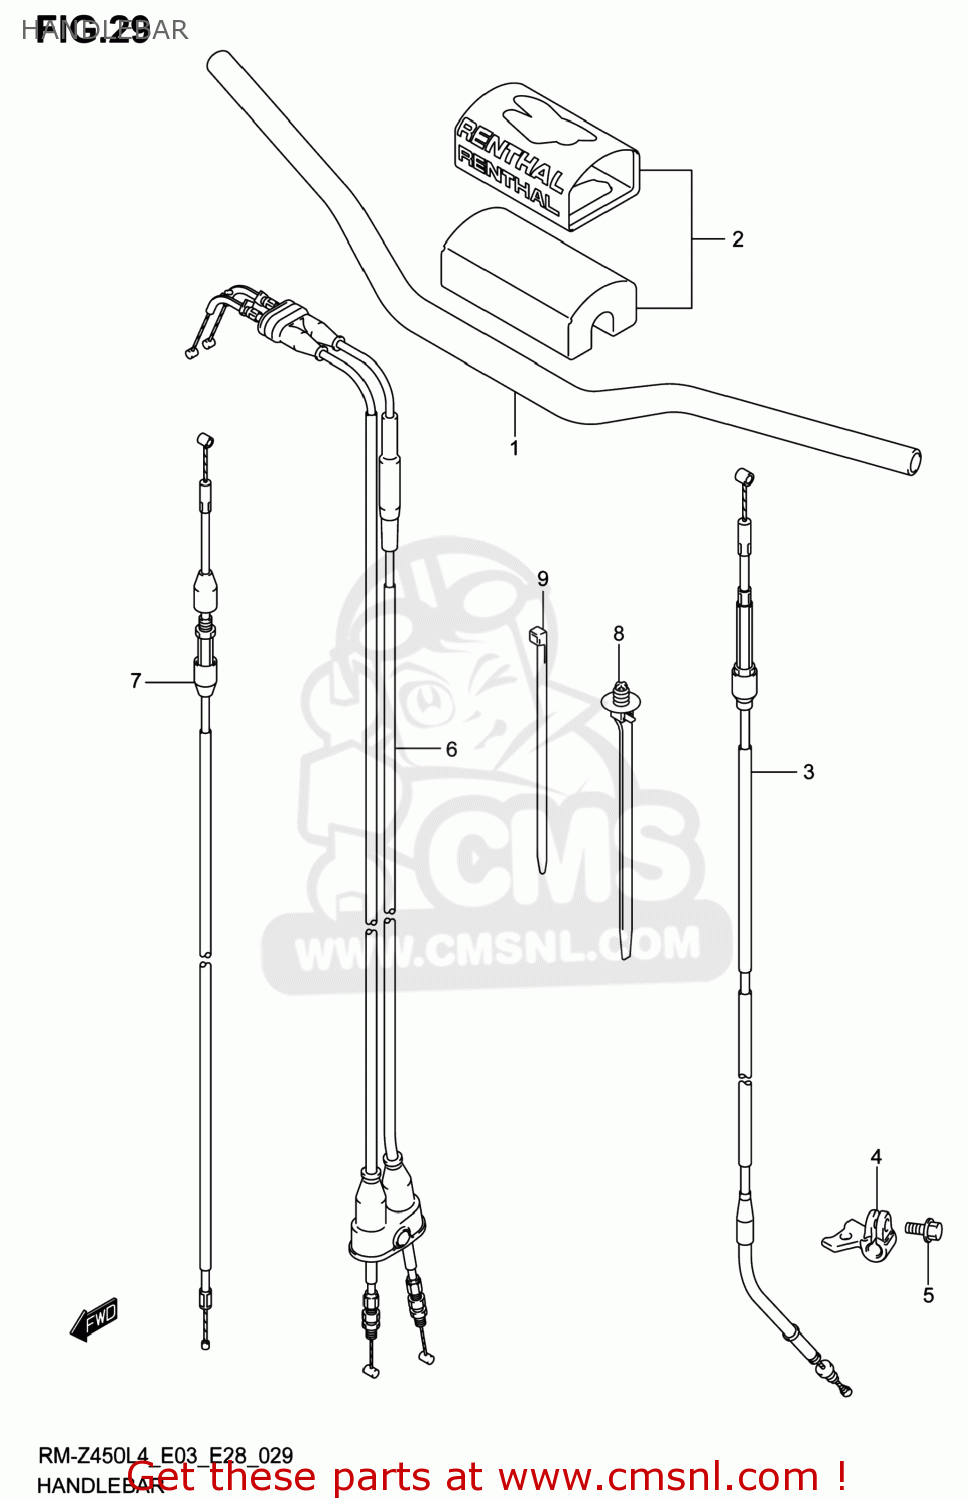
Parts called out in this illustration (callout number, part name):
1	HANDLEBAR
2	PAD SET,HANDLEBAR (NAS)
3	CABLE ASSY,CLUTCH
4	BRACKET,CLUTCH CABLE
5	BOLT
6	CABLE SET,THROTTLE
7	CABLE ASSY,HOT STARTER
8	CLAMP(L:154)
9	CLAMP(L:145)
